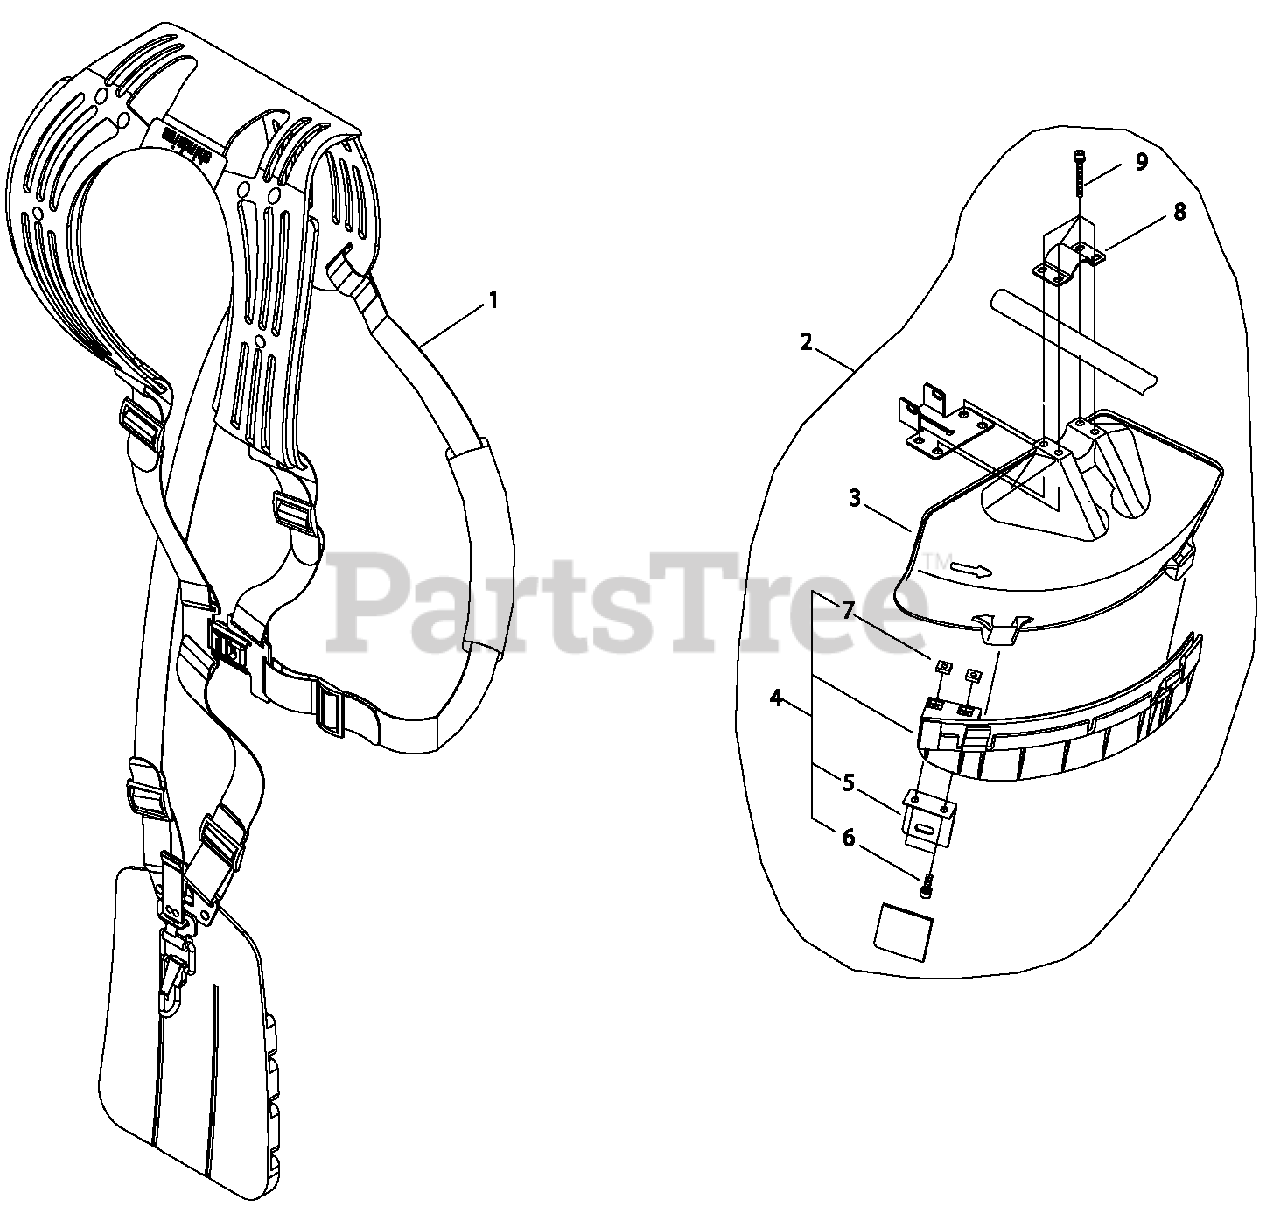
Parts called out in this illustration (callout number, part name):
1	HARNESS ASSY
2	DEBRIS SHIELD KIT
3	SHIELD, DEBRIS
4	SHIELD GUARD KIT
5	KNIFE, TRIMMER LINE
6	SCREW - 5X16
7	NUT - 5
8	CLAMP - UPPER
9	SCREW - 5X45
